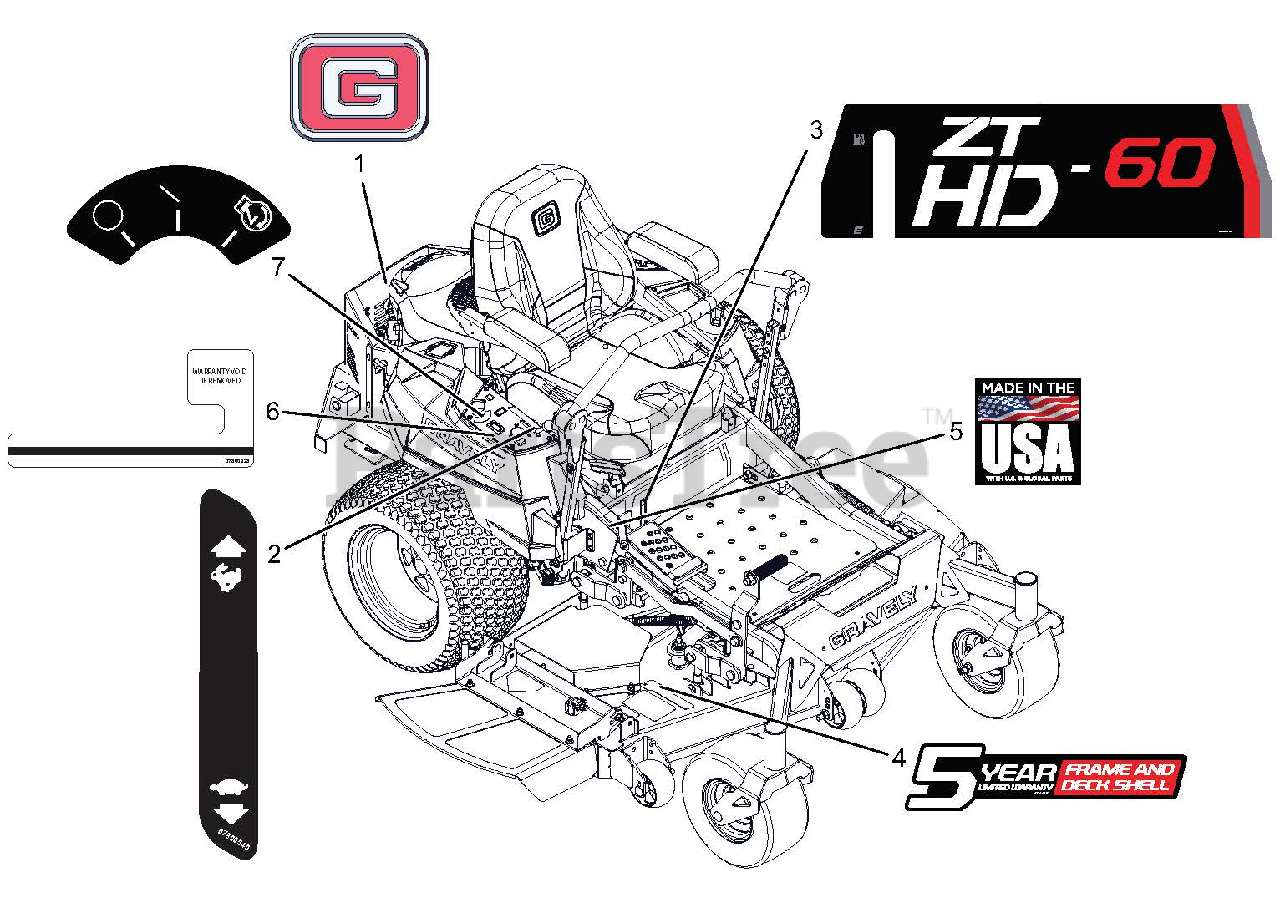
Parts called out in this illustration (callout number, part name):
1	DECAL, GRAVELY BRAND
2	DECAL, DASH DECAL
3	DECAL - 60HD
4	DECAL, DECK 5 YEAR-GRAVELY
5	DECAL, MADE IN USA
6	DECAL,HOURMETER - SECURITY
7	DECAL, KEYSWITCH
